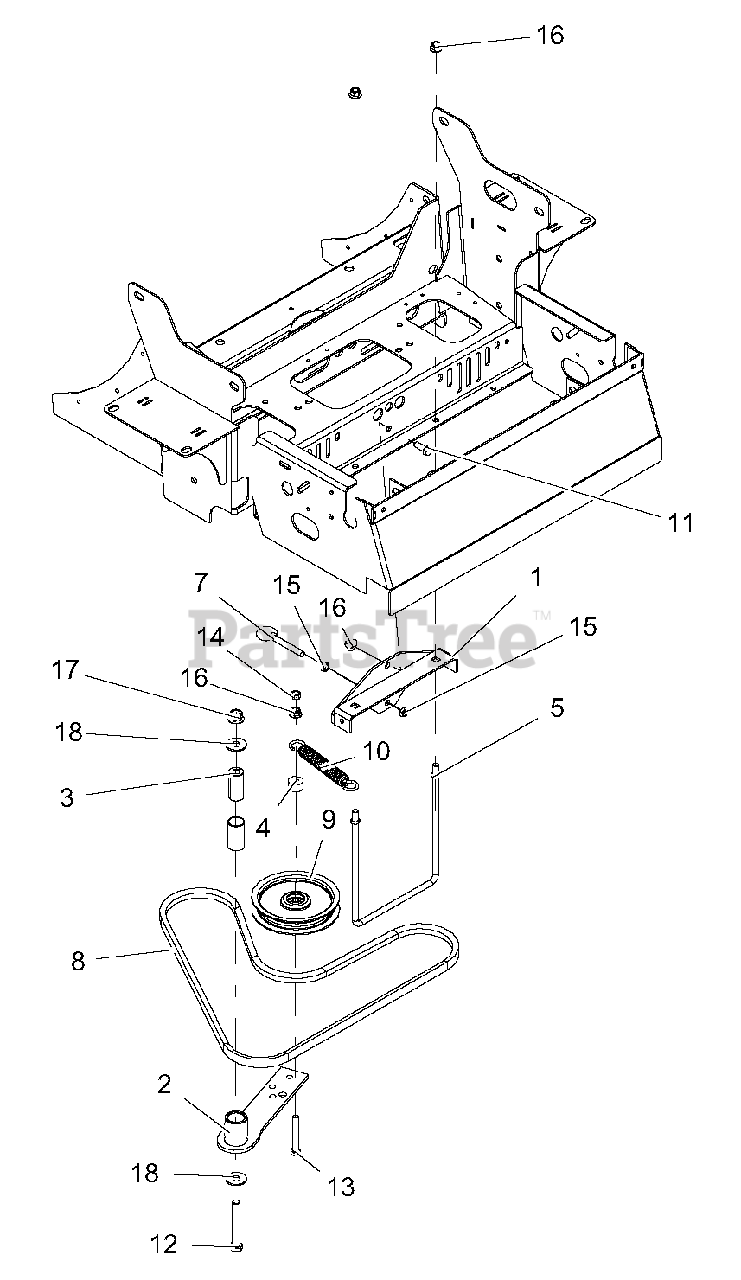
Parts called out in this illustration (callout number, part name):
1	WMT, SPRING ANCHOR BRKT-BLACK
2	WMT, IDLER ARM GROUND DRIVE-BLACK
3	BSHG, SPCR .502X.997X2.03
4	SPACER .390X1.000X.562
5	ROD, BRAKE MTG
7	BOLT, EYE .375-16
8	BELT, B RAW COGGED
9	IDLER, FLAT 5.00 X 3.8
10	SPRG, EXTENSION
11	BLT-HEX .38-16X1.00 GR5 YWZC
12	BLT-HEX .50-13X3.50 GR5 YWZC
13	BLT-HEX .38-16X2.75 GR5 YWZC
14	@NUT-LK-CTR .38-16 YWZC
15	NUT, JAM .375-16 YWZC
16	NUT-LK-NYL-FLG .38-16 YWZC
17	NUT-LK-NYL-FLG .50-13 YWZC
18	@WSHR-FL-STL.563X1.38X.109YWZC
